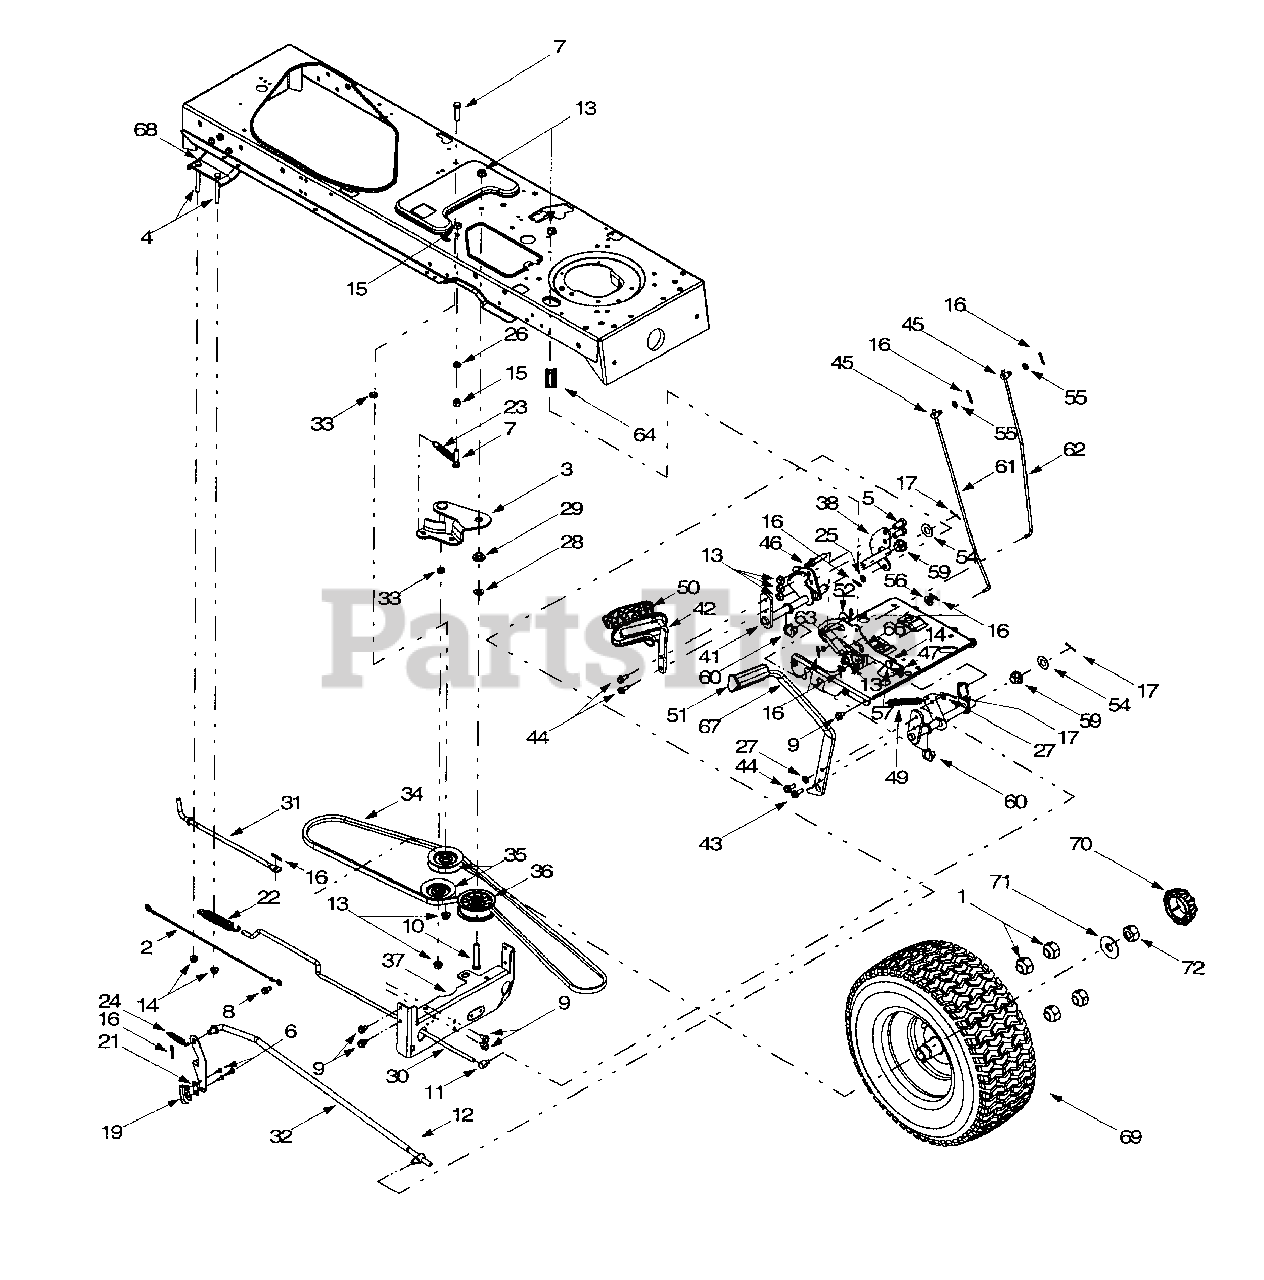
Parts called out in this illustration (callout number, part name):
1	Lug Nut, 3/4-16
2	Reverse/Ground Wire Harness Adapt
3	Double Idler Bracket Assembly
4	Hex Cap Screw, 5/16-18 x 3.00
5	Hex Cap Screw, 3/8-16 x .75
6	Screw, #8-18 x.5
7	Hex Cap Screw, 3/8-16 x 1.5
8	Self-tapping Screw, 1/4-20 x .50
9	Self-tapping Screw, 5/16-18 x .625
10	Hex Cap Screw, 3/8-16 x 2.25
11	Ferrule, 5/16-18
12	Ferrule, 3/8-24
13	Flange Lock Nut, 3/8-16
14	Flange Lock Nut, 5/16-18
15	Hex Nut, 3/8-16
16	Internal Cotter Pin
17	Cotter Pin
18	Cable Tie
19	Short Spring Switch
20	Push-mount Cable Tie
21	Insulator Nut Plate
22	Extension Spring, .59 x 4.0
23	Extension Spring, .5 x 3.5
24	Extension Spring, 3/8 x 1.44
25	Flat Washer, .385 x .62 x .063
26	Lock Washer, 3/8
27	Flat Washer, .344 x .688 x .065
28	Flat Washer, .407 x .812 x .135
29	Shoulder Spacer, .38
30	Hydrostatic Control Rod
31	Hydrostatic Bypass Rod
32	Hydrostatic Brake Rod
33	Spacer, .376 x .625 x .22
34	Drive Belt
35	V-idler Pulley, 3.06
36	Flat Idler Pulley, 2.75
41	Drive Control Assembly
42	Hydro Pedal Assembly
43	Self-tapping Screw, 5/16-18 x .875
44	Self-tapping Screw, 5/16-18 x .75
45	Ferrule, 1/4-20
46	Pin, 3/8-16 x 2.43
47	Compression Spring, .34 OD x 1.0
48	Extension Spring, .50 OD x 1.41
49	Extension Spring, .50 OD x 6.37
50	Drive Pedal Pad
51	Brake Pedal Pad
52	Flat Washer, .411 x 1.25 x 1.0
53	Flat Washer, .281 x .50 x .063
54	Flat Washer, .64 x 1.24 x .06
55	Flat Washer, .344 x .062 x .03
56	Flat Washer, .406 x .875 x .105
57	Shoulder Screw, .437 x 1.62
58	Shoulder Screw, .5 x .434
59	Hex Flange Bearing
60	Split Hex Flange Bearing
61	Cruise Control Rod
62	Brake Lock Control Rod
63	Cruise Latch
64	Spacer, 5/16 x 1.54
66	Drive Lockout Bracket
70	Hub Cap
71	Flat Washer, .780 x 1.59 x .062
72	Jam Nut, 3/4-16
